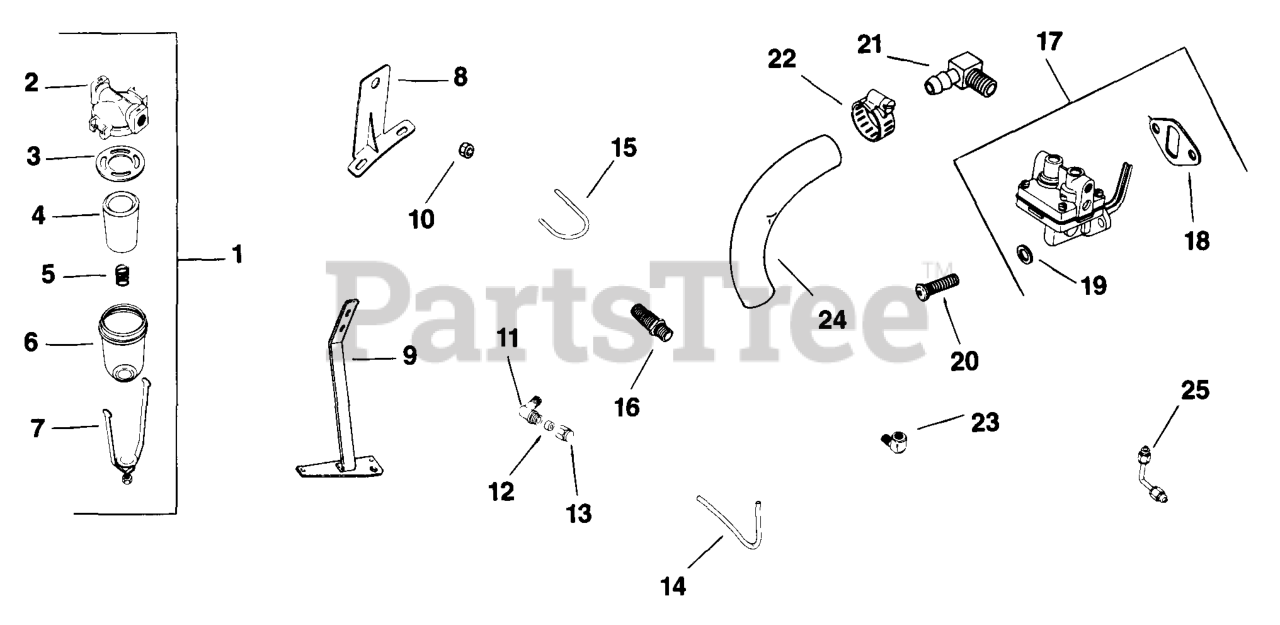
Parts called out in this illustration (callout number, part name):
1	FILTER - (#DSC)
3	GASKET - DISCONTINUED
4	ELEMENT - DISCONTINUED
5	SPRING - DISCONTINUED
7	RETAINER - DISCONTINUED
8	BRACKET, FUEL FILTER - DISC
11	ELBOW - (#DSC)
16	NIPPLE - DISCONTINUED
20	SCREW, POZ TRS HD 1/4-20X5/8" - DISCONTINUED
21	CONNECTOR, 90 DEG. HOSE
22	CLAMP, HOSE 1/2" USE 25 237 14-S
23	ELBOW, STREET 1/8 NPTF BRASS USE 25 054 13-S
24	LINE - DISCONTINUED
25	LINE - DISCONTINUED
